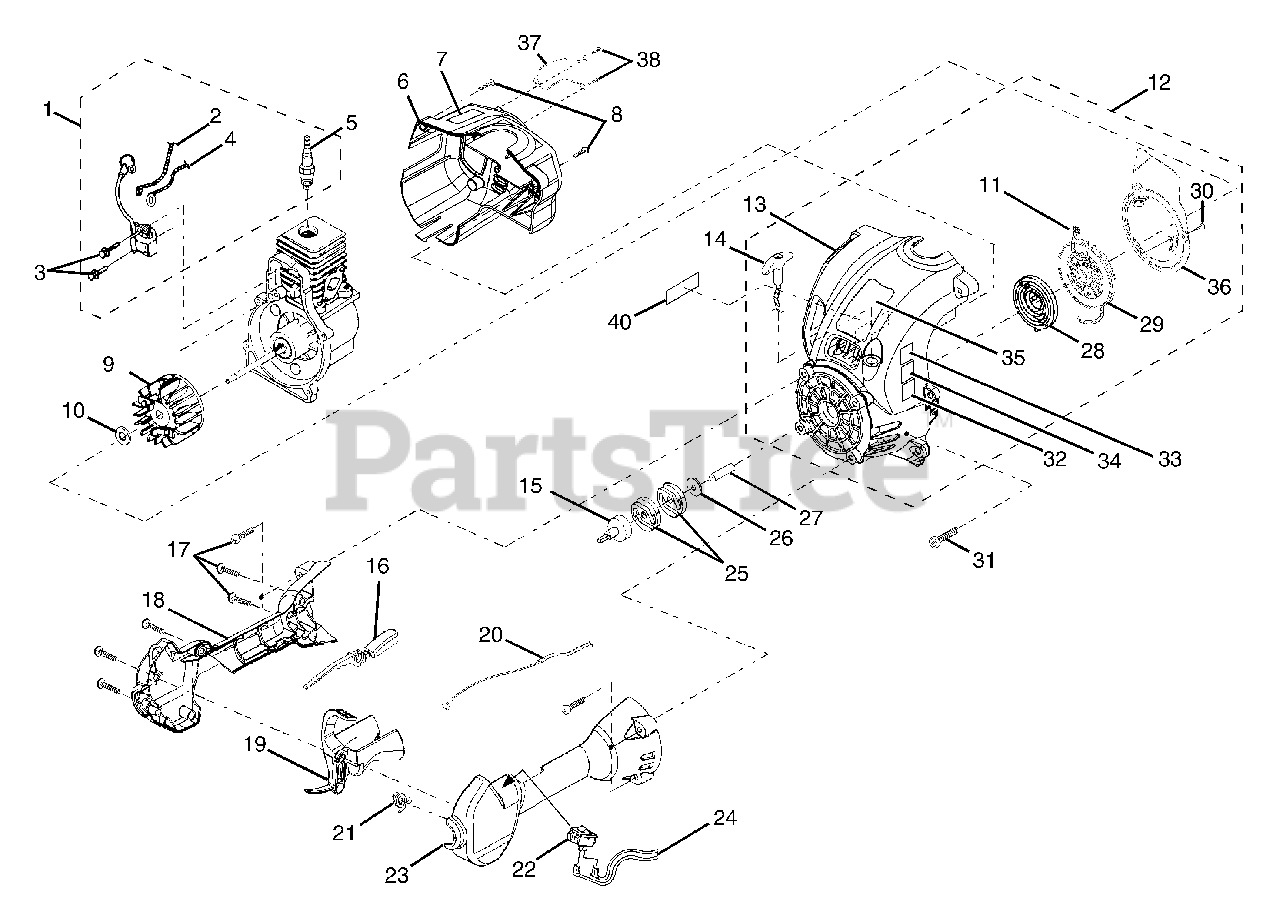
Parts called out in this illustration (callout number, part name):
1	IGNITION KIT
2	ELECTRICAL LEAD
4	ELECTRICAL LEAD
5	SPARK PLUG
6	REAR COVER
7	LOGO PLATE
8	SCREW (10-14 x 7/8))
9	ROTOR AND PAWL ASSEMBLY
11	STARTER ROPE (42 in.)
12	STARTER ASSEMBLY
13	STARTER HOUSING AND EYELET
14	ERGO GRIP
15	DRUM AND CONNECTOR
16	INTERLOCK TRIGGER
18	CONTROL HANDLE / RH
20	THROTTLE CABLE
22	SWITCH
23	CONTROL HANDLE / LH
24	ELECTRICAL LEADS
25	CLUTCH DISK ( ST185 & ST385 )
26	WASHER
28	SPRING & CONTAINER
29	STARTER PULLEY
32	DECAL, 113 POWER SOUND
33	DECAL, ZIP START
34	DECAL, CE
35	DECAL, MODEL
36	AIR BAFFLE PLATE
37	MUFFLER GUARD
40	DECAL, FUEL RATIO MIXTURE
